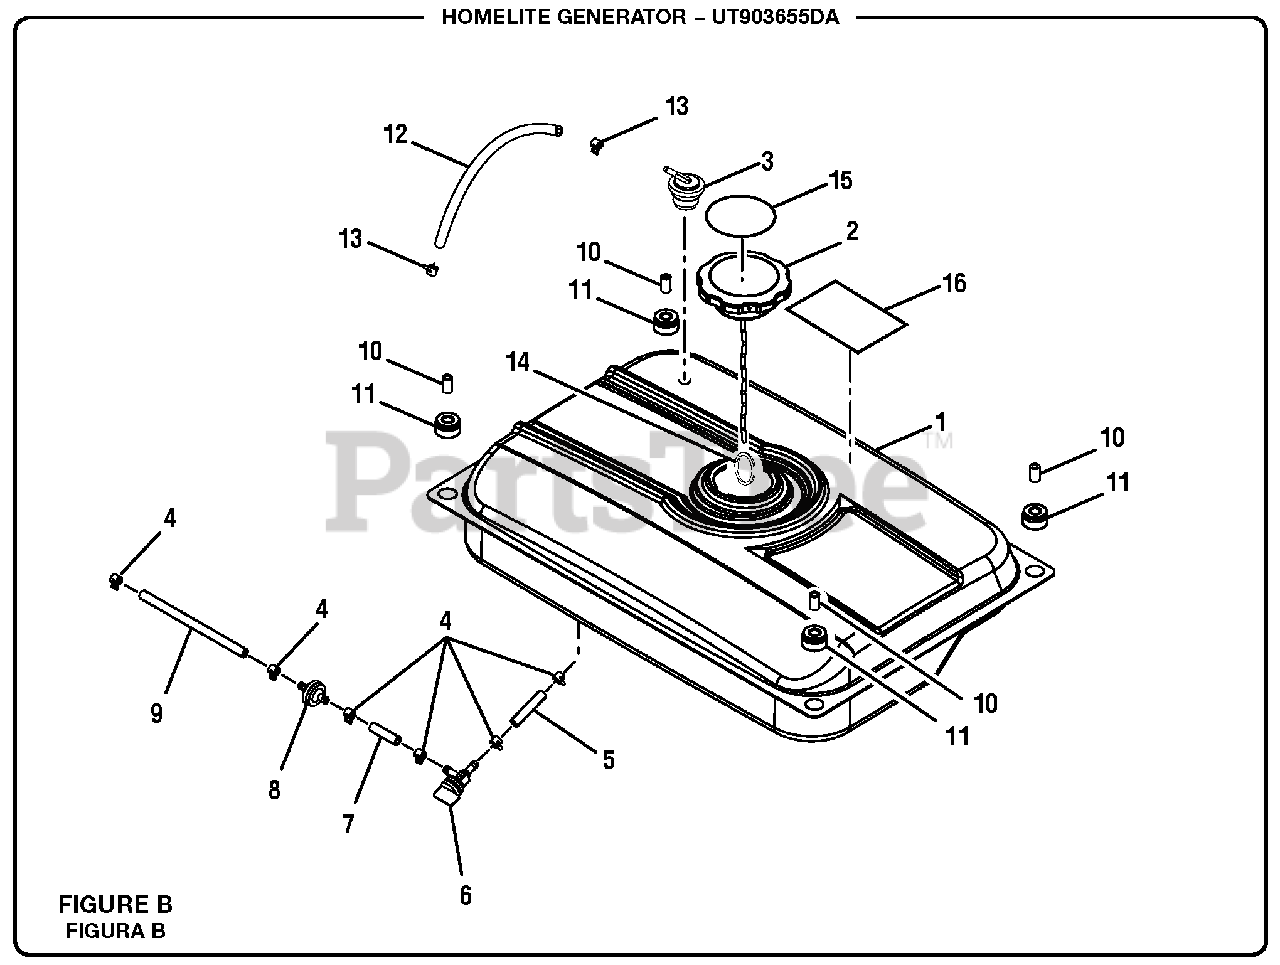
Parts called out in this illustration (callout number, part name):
1	Fuel Tank
3	Vapor Vent
4	Clamp (1/2 in.)
5	Fuel Hose (45 mm)
6	Fuel Shut Off Valve
7	Fuel Hose (35 mm)
8	Fuel Filter
9	Fuel Line (144 mm)
12	Vent Hose
13	Fuel Line Clamp (7/16 in.)
14	Ring Clip
15	Fuel Stabilizer Label
16	Fuel Stabilizer Label (Fr/Sp)
